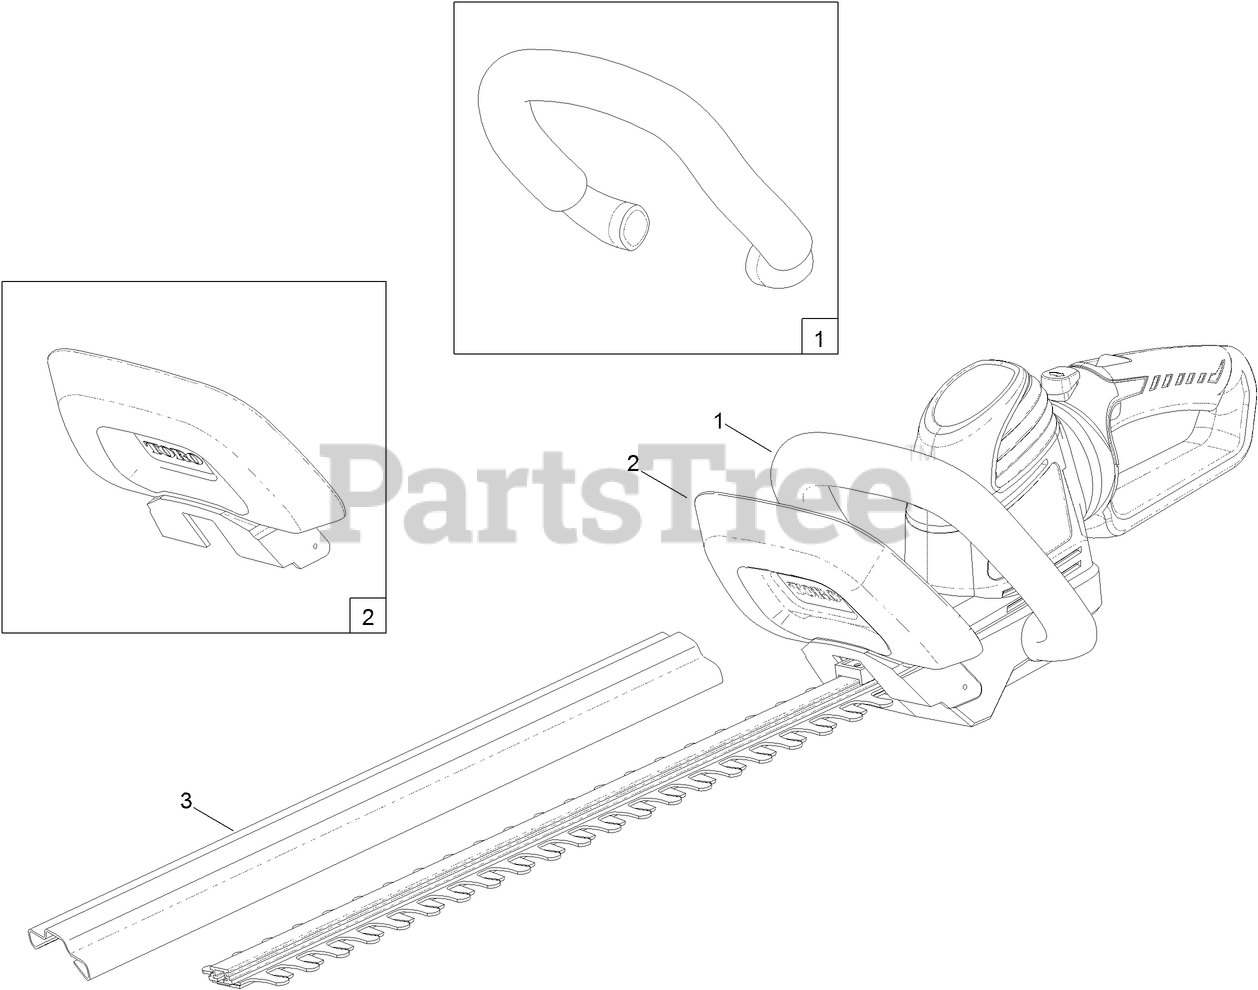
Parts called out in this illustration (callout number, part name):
1	HANDLE-ASSIST
2	GUARD ASM
3	SHEATH-BLADE
